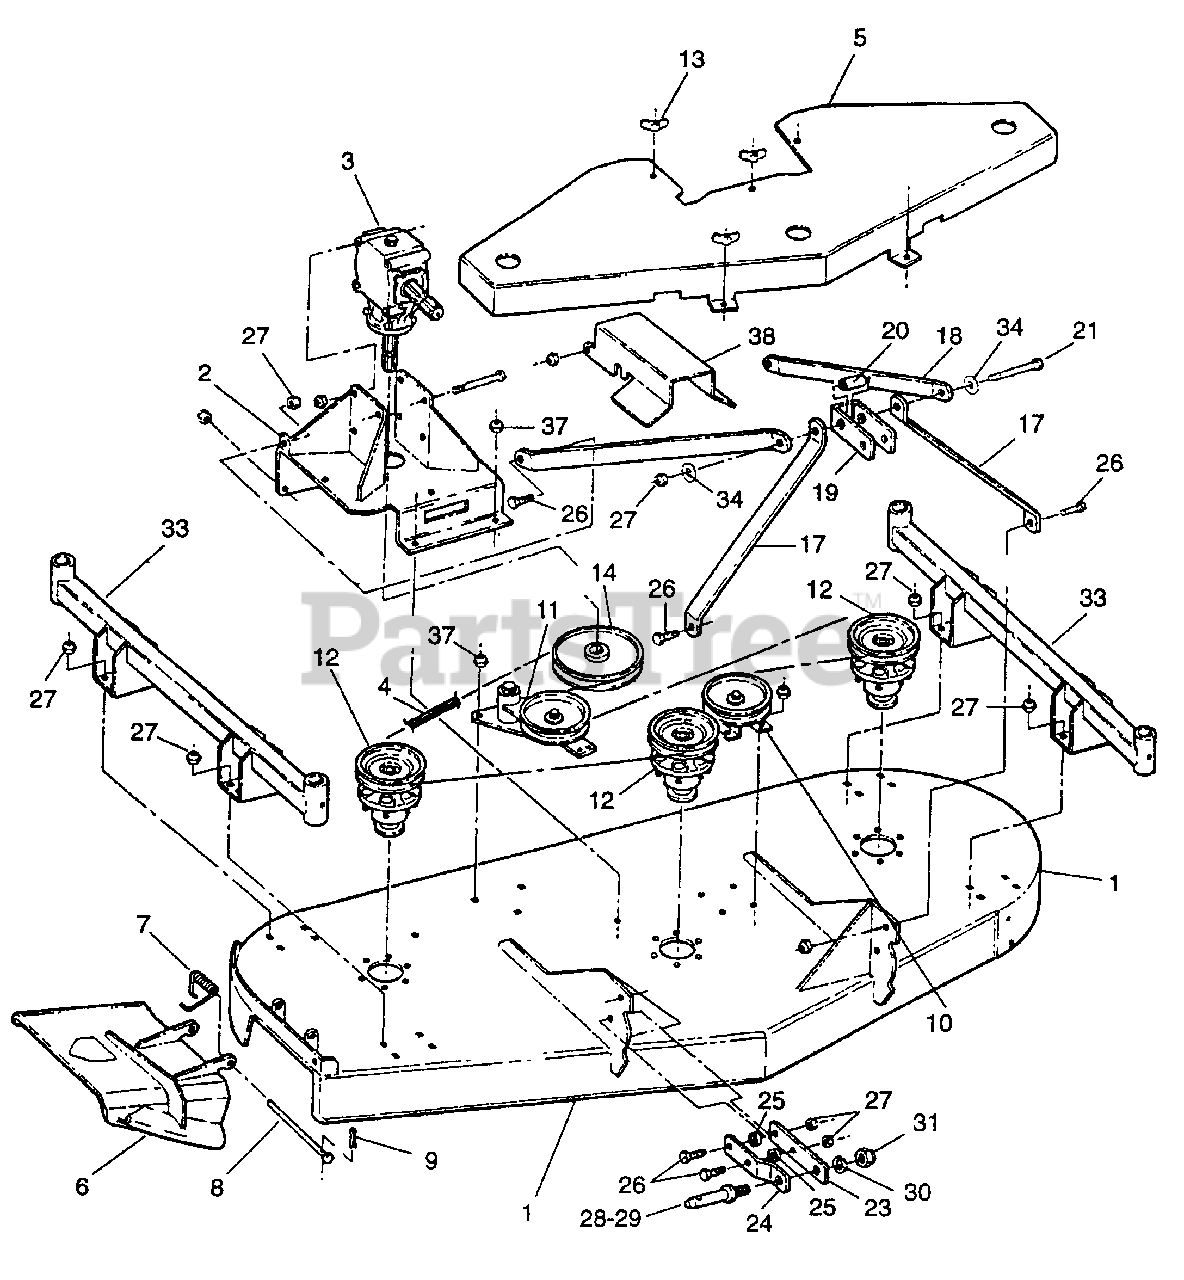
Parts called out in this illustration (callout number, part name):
1	WELDMENT, 73" Finishing Deck
2	WELDMENT, Gearbox Mount
3	GEARBOX, 1:1.90 Right Angle
4	BELT, 165.5" HB Section
5	COVER, Belt
6	WELDMENT, 73" Discharge Chute (OFZ)
7	SPRING, Chute
8	HINGE PIN, Chute
9	PIN, 3/32 x 1.0 Cotter
10	GROUP, Fixed Idler
11	GROUP, Spring-Loaded Idler
12	GROUP, Spindle
13	WINGNUT, 3/8" NYL Ring
14	PULLEY, 12" Split Steel
17	BAR, Front Hitch
18	BAR, Rear Hitch
19	LINK, Hitch
20	SLEEVE, Hitch Bolt
21	BOLT, 1/2-13 X 5 GD5 YZ
23	ARM, Pivoting Hitch
24	ARM, Bent Pivoting Hitch
25	SLEEVE, 3/4 O.D. x 1/2 I.D.
26	BOLT, 1/2-13 X 1-1/2 GD5 CZ
27	NUT, 1/2-13 HEX NYLON LOCK
28	PIN, Hitch Lift Arm
29	PIN, Hitch Lift Arm,
30	WASHER, 7/8 Slotted,
31	NUT, 7/8 - 14 UNF Hex
33	WELDMENT, Caster Tube
34	WASHER, 1/2 x 63/64 Flat
37	NUT, 3/8-16 HEX NYLON LOCK
38	GUARD, Driveshaft
